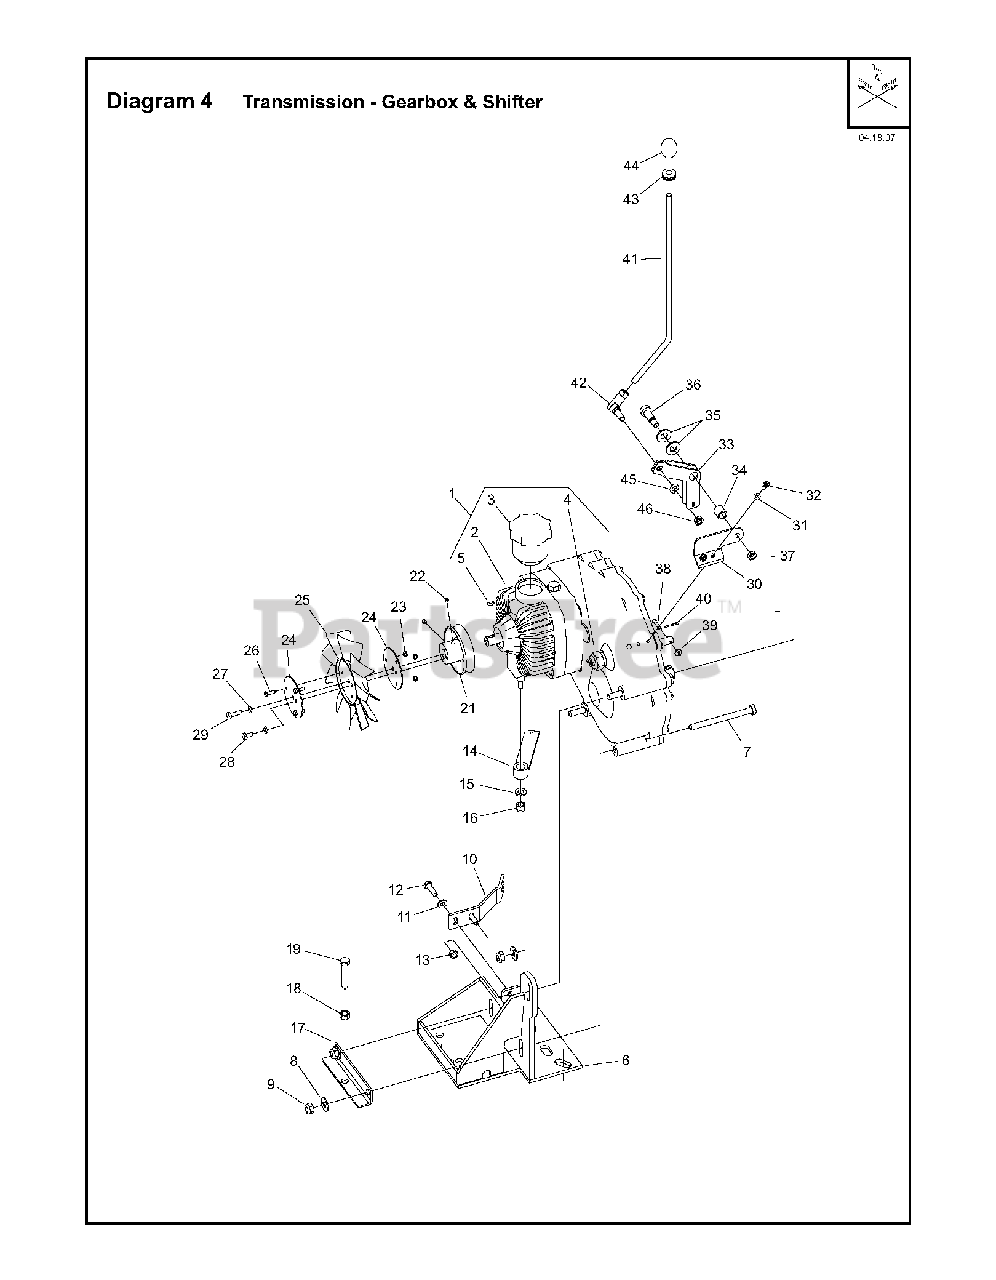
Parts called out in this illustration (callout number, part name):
1	GEAR BOX ASSY 1-SPEED
2	VARIATOR EATON TRANSMIS/
3	PLASTIC OIL RESERVOIR/
5	KEY. WOODRUFF (ANSI #404)
6	GEARBOX MTG BRACKET - BLACK
7	HHCS. M10 x 1.5 x 120 DIN931ZP
9	LOCKNUT. FIBER M10 DIN 985
10	CABLE BRACKET - BLACK
11	WASHER
13	LOCKNUT. FIBER M8 DIN 985 Z/P
14	SPEED CONTROL ARM - BLACK
16	LOCKNUT. FIBER .375-16 Z/P
17	TENSIONING BRACKET - BLACK
18	NUT
19	HHCS. M10 x 1.5 x 50 DIN933 ZP
21	TRANSMISSION PULLEY
22	SHSS. .25-20 x .375 CUP HK
24	FAN ATTACHMENT PLATE
25	BLADE. PLASTIC FAN
26	HHCS. M5 x 0.8 x 16 DIN933 Z/P
27	LOCKWASHER. HI-COLLAR .25
28	HHCS. .25-20 x .5 GR 5 Z/P
29	HHCS. .25-20 x .875 GR 5 Z/P
30	SHIFT PIVOT BRACKET - BLACK
31	LOCKWASHER. SPLIT M6
32	SHCS. LOW M6 X 1.0 X 20MM
33	LINK ASSY. SHIFTER
36	SHSHS. .375-16 UNC x 1 Z/P
38	PIN. CLEVIS .18DIA Z/P
40	PIN. COTTER .0937 x .75 Z/P
41	ROD. SHIFTER - PRO 35III
45	LOCKWASHER. SPLIT .375
